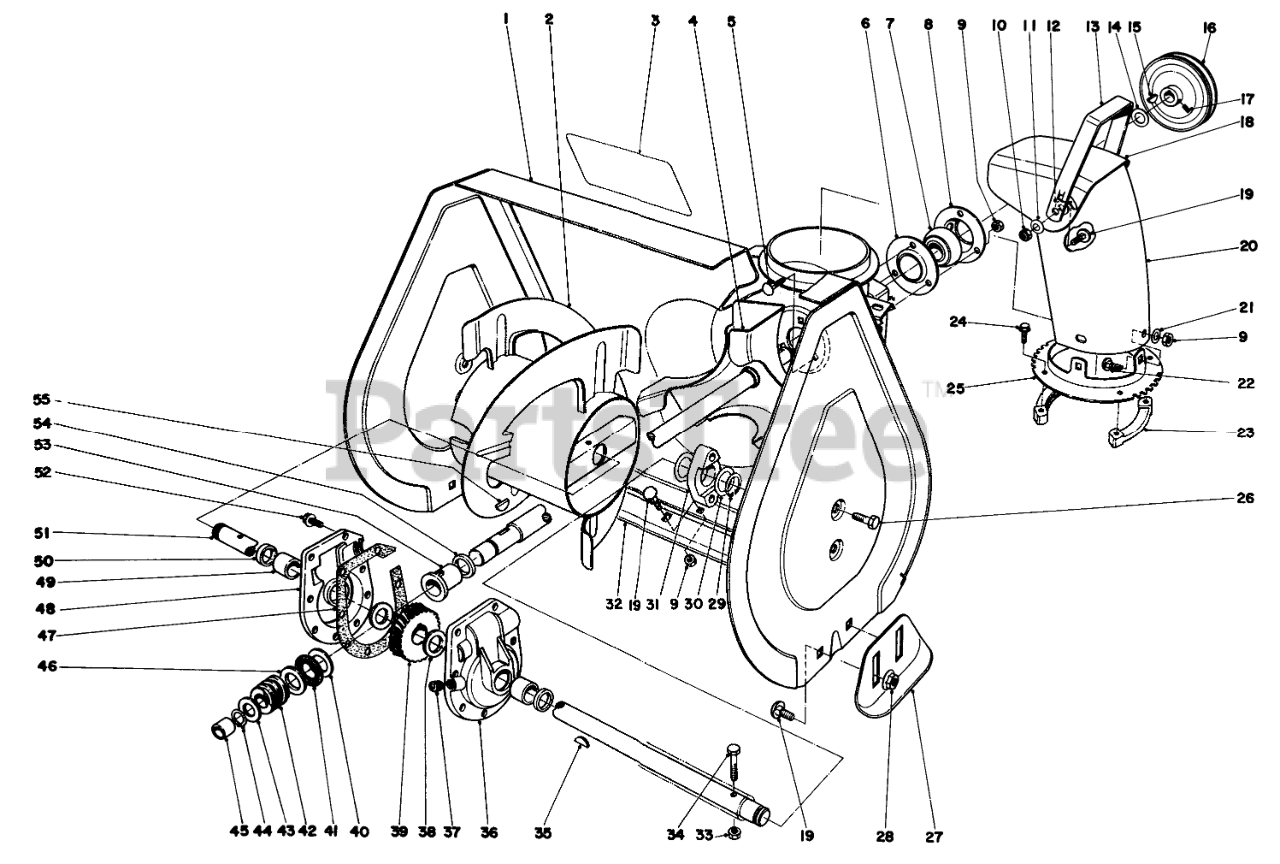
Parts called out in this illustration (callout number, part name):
5	BOLT-CARR
6	FLANGE-CUP, BEARING
7	Ball Bearing
8	FLANGE-CUP, BEARING
9	NUT-LOCK, NI
10	NUT-LOCK, CONE
11	WASHER-BELLEVILLE
12	WASHER-RUBBER
14	WASHER
15	KEY-WOODRUFF
16	PULLEY
17	SCREW-SET, SQH
19	BOLT-CARR
21	WASHER-PLAIN
22	SCREW-CARR
23	RING-CHUTE, RETAINER
24	SCREW-SPECIAL
26	SCREW-THD ROLL, HWH
28	NUT-HF
29	RING-RETAINING
30	WASHER
34	SCREW-HH
35	KEY-WOODRUFF
37	PLUG-PIPE, SQH
38	WASHER-THRUST
40	WASHER-THRUST
41	BEARING-THRUST
43	WASHER-THRUST
44	RING-SNAP
45	BUSHING
46	WASHER-THRUST
49	BUSHING
50	SEAL-OIL
51	AUGER SHAFT
52	SCREW-TAPTITE
53	BUSHING-INPUT
54	RING-QUAD
55	KEY-WOODRUFF
